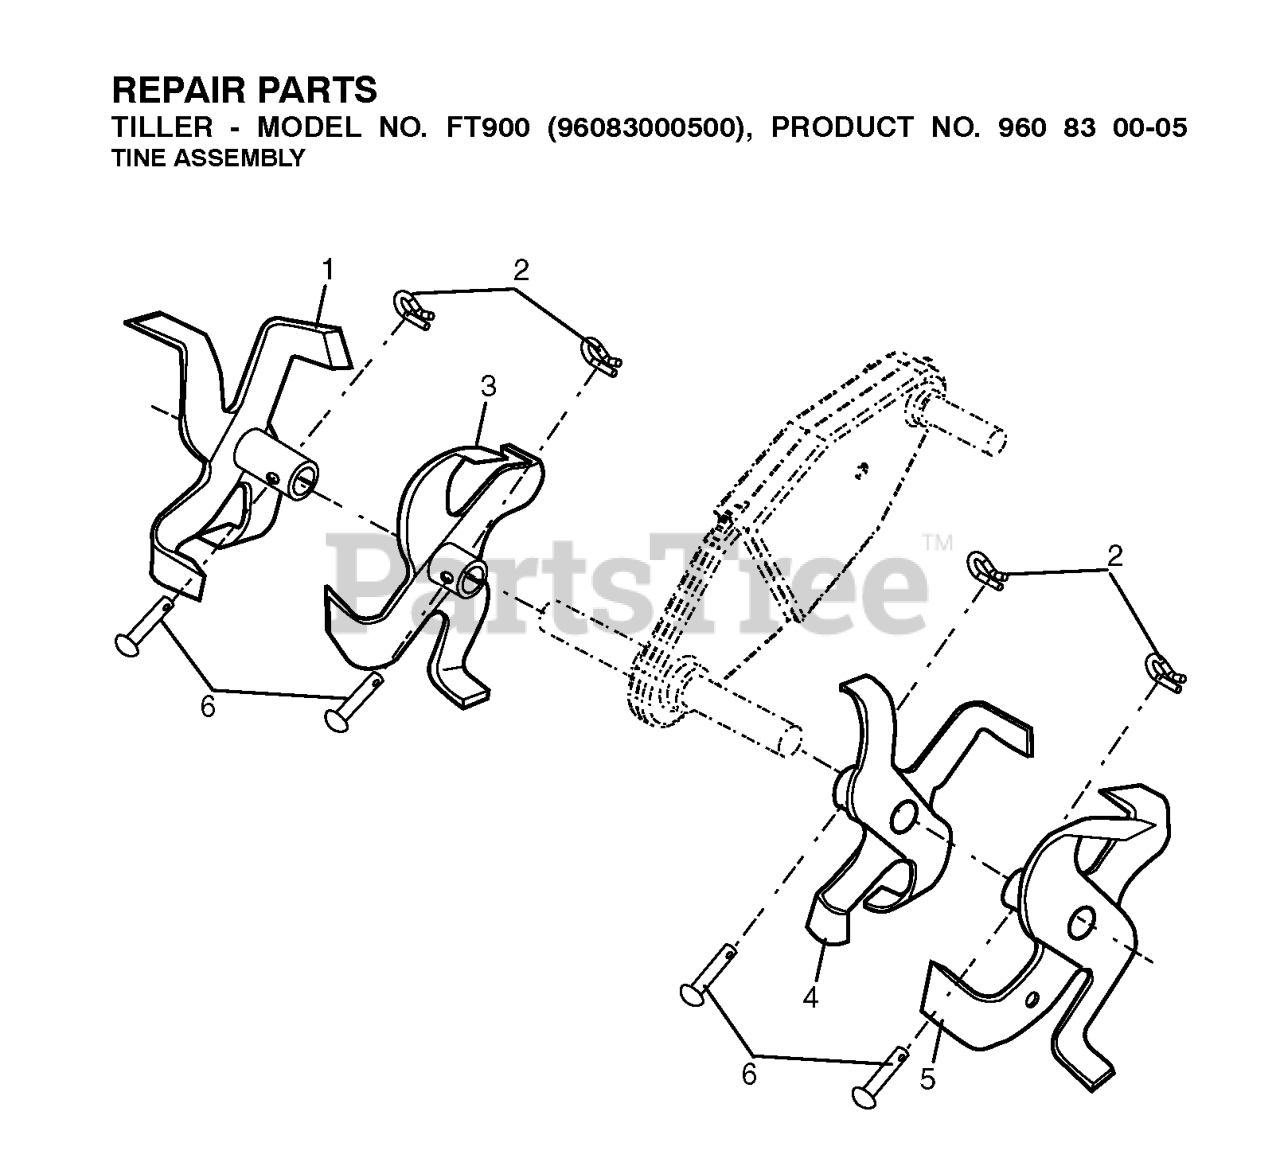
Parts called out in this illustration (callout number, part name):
1	RP TINE
2	SPRING RETAINER
3	RP TINE
4	RP TINE
5	RP TINE
